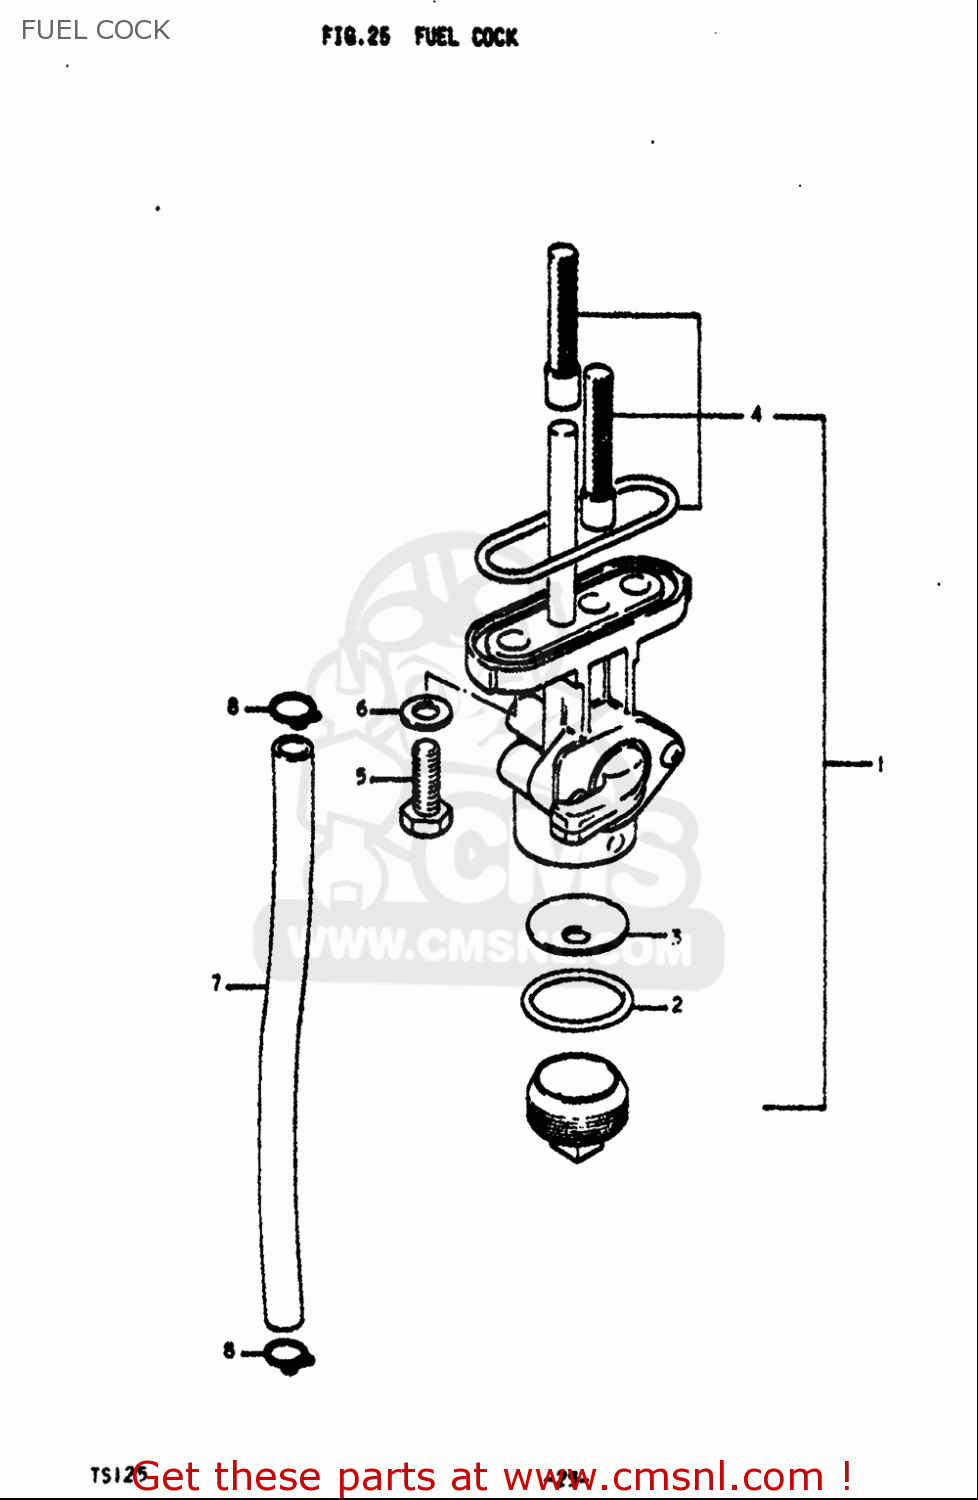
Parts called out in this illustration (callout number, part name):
1	COCK ASSY,FUEL
2	GASKET,FILTER (NAS)
3	NET,STRAINER
4	FILTER SET,FUEL COCK
5	BOLT(6X20)
6	GASKET(5.8X13X1.2) (NAS)
7	HOSE(5X9X600)
8	CLIP
